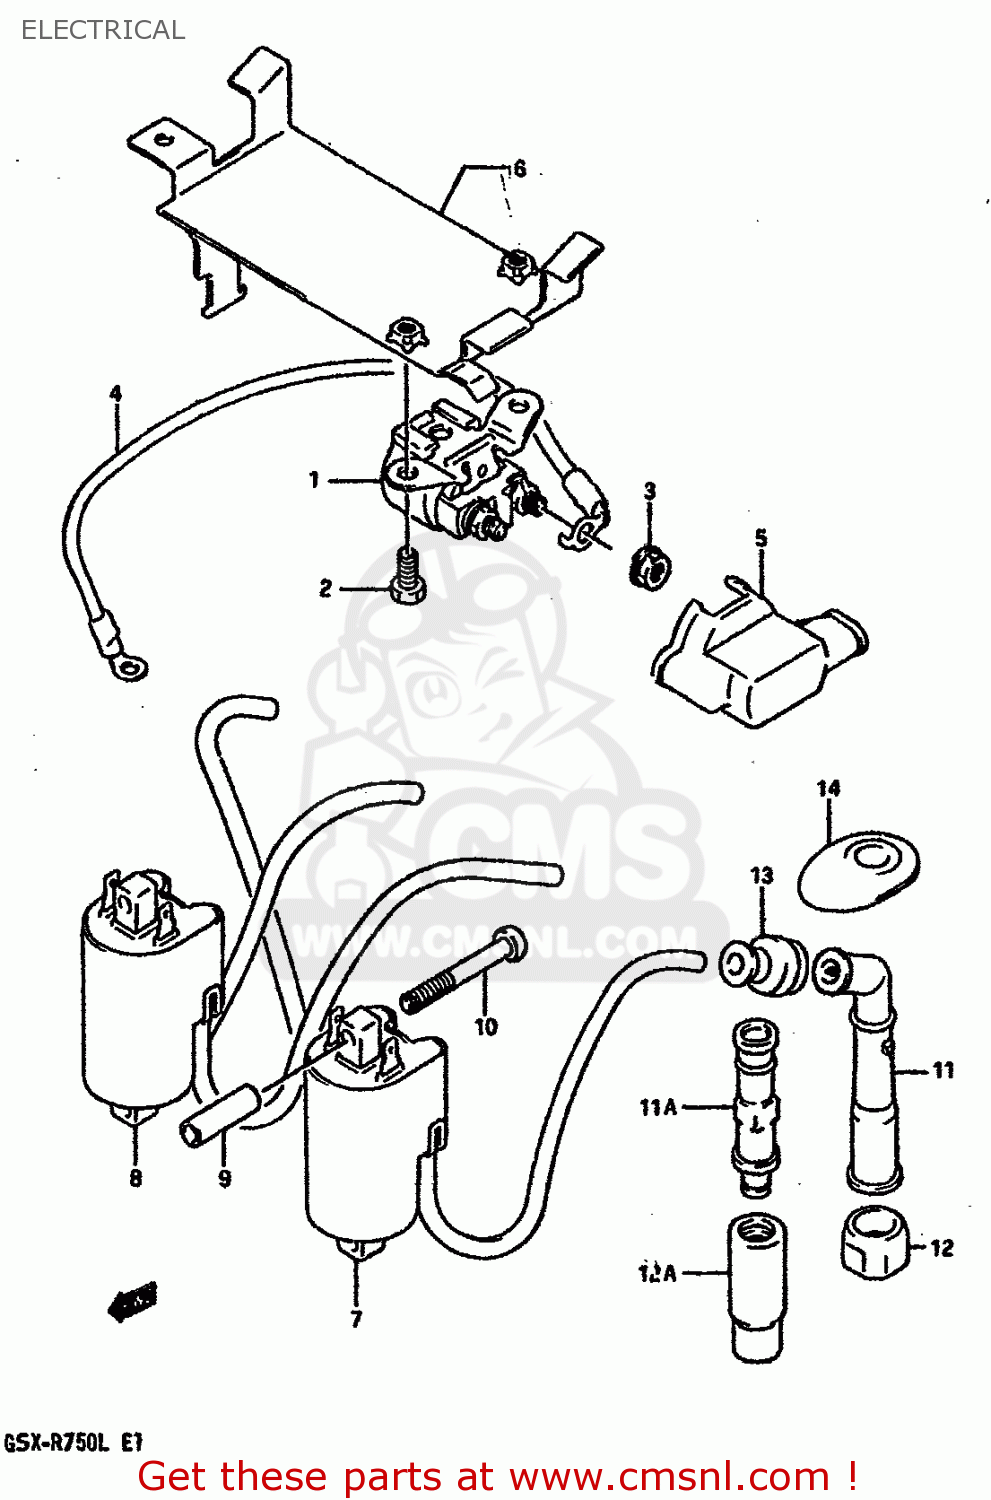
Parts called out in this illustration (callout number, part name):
1	RELAY ASSY,STARTING MOTOR
2	SCREW(6X8)
3	NUT
4	WIRE,STARTER MOTOR LEAD
5	COVER,RELAY ASSEMBLY
6	HOLDER COMP,ELECTRONIC PARTS
7	COIL ASSEMBLY,IGNITION (1-4)
8	COIL ASSEMBLY,IGNITION
9	SPACER(6.4X10X32)
10	SCREW
11	CAP,SPARK PLUG
11A	CAP,SPARK PLUG
12	SEAL,SPARK PLUG
12A	SEAL,SPARK PLUG
13	SEAL,HIGH TENSION CORD
14	COVER,SPARK PLUG CAP
